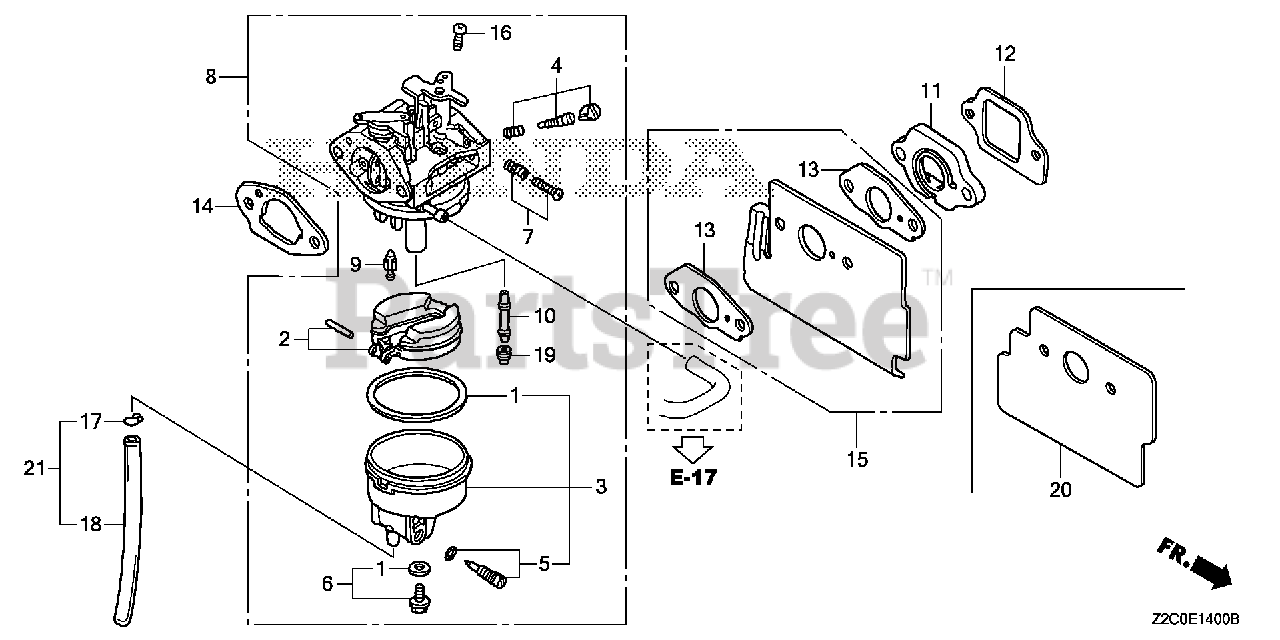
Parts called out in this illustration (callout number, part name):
1	GASKET SET
2	FLOAT SET
3	CHAMBER SET, FLOAT
4	SCREW SET (CARBURETOR NO.)
5	SCREW SET, DRAIN (ADVENTURE GREEN) (CARBURETOR NO.)
6	SCREW SET B
6	SCREW SET
7	SCREW SET (THROTTLE STOP) (CARBURETOR NO.)
8	CARBURETOR ASSY. (BB61G C)
8	CARBURETOR ASSY. (BB65T A)
9	VALVE, FLOAT (CARBURETOR NO.)
10	NOZZLE, MAIN (CARBURETOR NO.)
11	INSULATOR, CARBURETOR
12	GASKET, INSULATOR
14	GASKET, CARBURETOR (Honda Code 5580253). (CHOKE SIDE)
16	SCREW, PAN (5X6)
17	CLIP, TUBE (B6.5)
18	BULK HOSE, VINYL (4X7X8000) (95003-07(95003-07001-60M) (CARBURETOR NO.)
19	JET, MAIN (#62) (Honda Code 0635482). (CARBURETOR NO.)
19	JET, MAIN (#65) Use up to Engine SN BB30A D.
19	JET, MAIN (#68) Use up to Engine SN BB30A D.
19	JET, MAIN (#70) Use up to Engine SN BB30A D.
19	JET, MAIN (#72) Use from Engine SN 6185281.
20	GUIDE, AIR
21	TUBE ASSY., DRAIN
